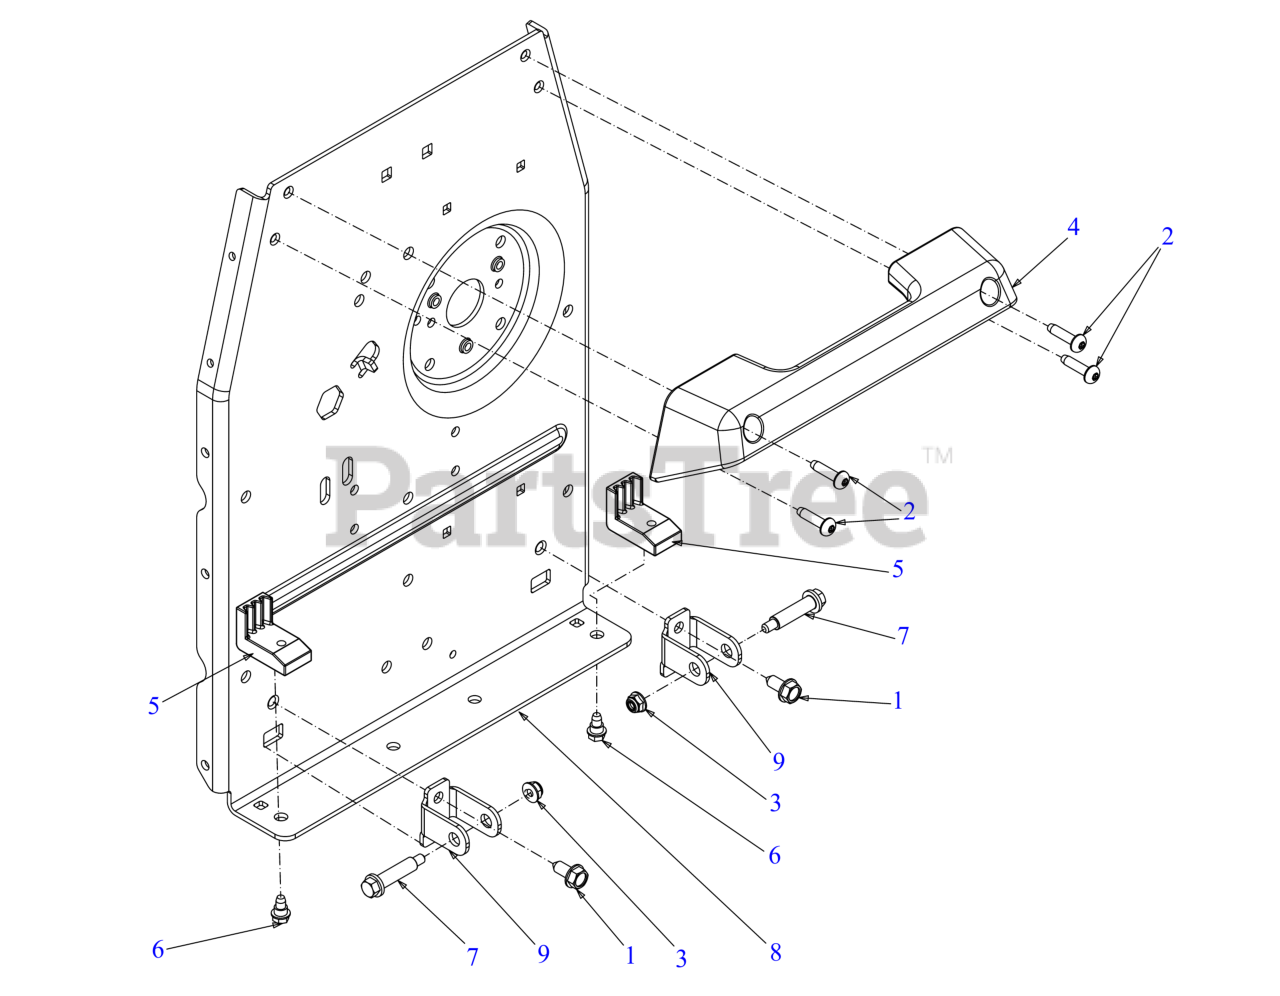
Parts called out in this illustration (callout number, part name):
1	SCREW 5/16-18 x .750
2	SCREW 1/4-20 x 1.0
3	FLANGE LOCK NUT
5	BUMPER PAD
6	SHOULDER SCREW 1/4-20 x .50
7	SHOULDER SCREW .37
